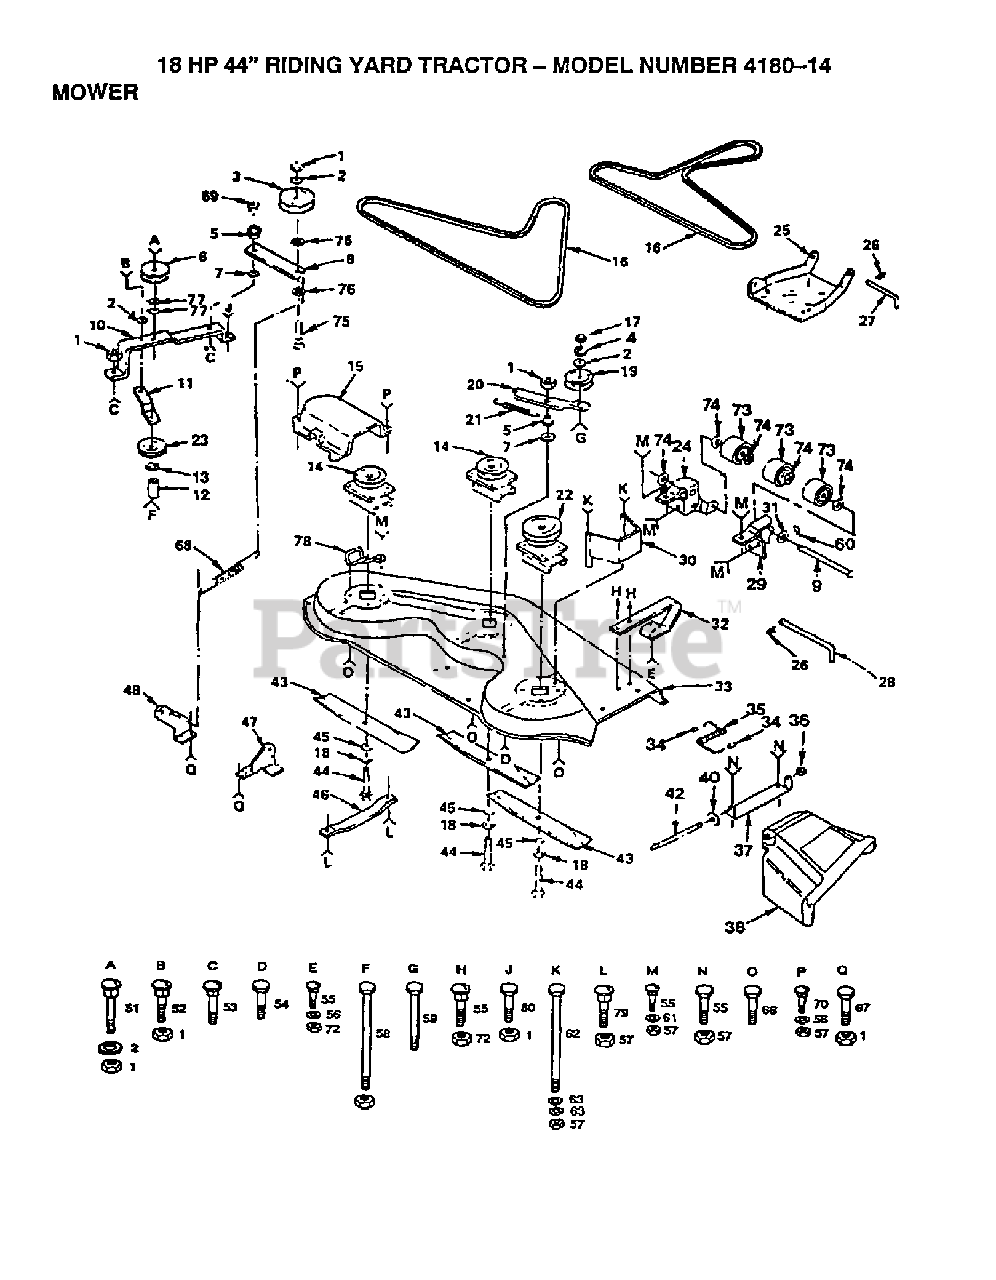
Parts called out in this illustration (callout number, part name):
1	LOCKNUT
3	PULLEY IDLER
4	WASHER, LOCK 3/8
5	SPACER RETAINER
6	IDLER-INSIDE T
7	WASHER, WEAR LT (1 2)
8	ARM IDLER
9	PIVOT PIN T
10	BAR-SUPPORT YT
11	BRACE-IDLER YT
14	JACKSHAFT YT
15	GUARD YT
16	V-BELT T
17	NUT.HEX.3/8-16UNC
19	IDLER.FLAT.GTV
20	ARM-IDLER YT
21	SPRING T
22	JACKSHAFT YT
23	IDLER-FLAT T
24	BRACKET LH YTH
25	LINK,PARALLEL
26	SPRING.RETAINER
27	ROD,FRT PARALL LT
28	HINGE PIN T
29	BRACKET RH YTH
30	GUARD BELT HYT
31	WASHER
32	Poulan TBD
33	HOUSING
34	CAP-SLEEVE LT
35	DEFLECTOR SPRG T
36	NUT PUSH M
38	DEFLECTOR SHIELD
40	WASHER
42	ROD-HINGE T
43	BLADE
44	BOLT.3/8-24X1-1/2
45	WASHER
46	RUNNER LH
47	BRKT SUSP REAR RH
51	BOLT
55	BOLT
56	WASHER
57	LOCKNUT
59	SCREW YT
60	COTTER PIN
61	WASHER M
63	WASHER M
68	SPRING.EXT.8.5"
69	LOCKNUT
70	BOLT.5/16-18.
72	Lock Nut
73	ROLLER T
75	BOLT
76	WASHER
77	WASHER
78	BELT RETIANER
79	BOLT
80	BOLT
